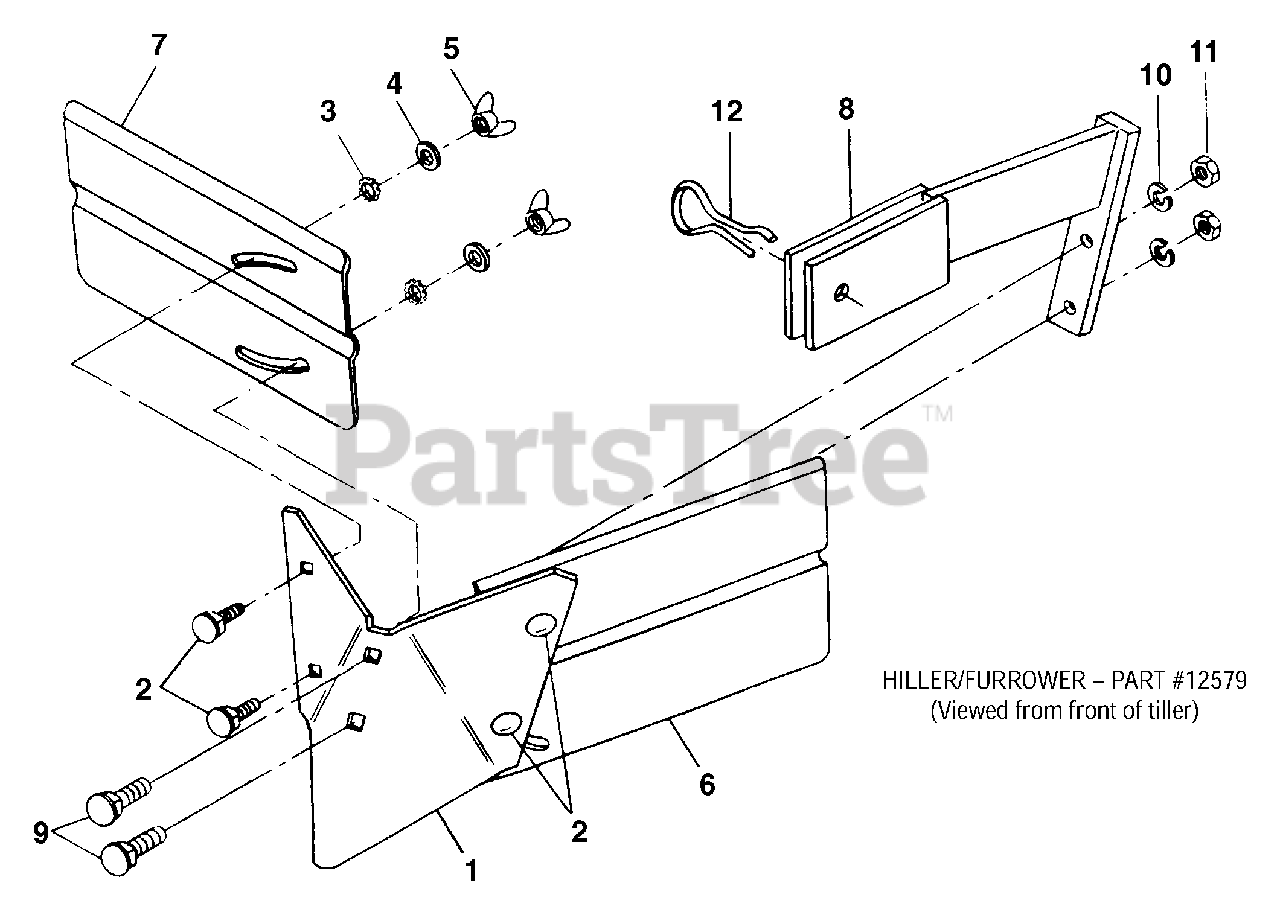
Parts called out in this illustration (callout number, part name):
1	Furrower, blade only
2	Carriage bolt, 5/16-18 x 3/4
3	Star Washer, ext. tooth, 5/16
4	Washer, plain, 5/16 S.A.E.
5	Wing nut, 5/16-18
6	Hiller wing, left
7	Hiller wing, right
8	Bracket, blade mounting
9	Carriage bolt, 3/8-16 x 1- 1/2
10	Lockwasher, 3/8, plated
11	Nut, hex, 3/8-16, plated
12	Pin, clinch
12579	Hiller/Furrower, complete attachment
